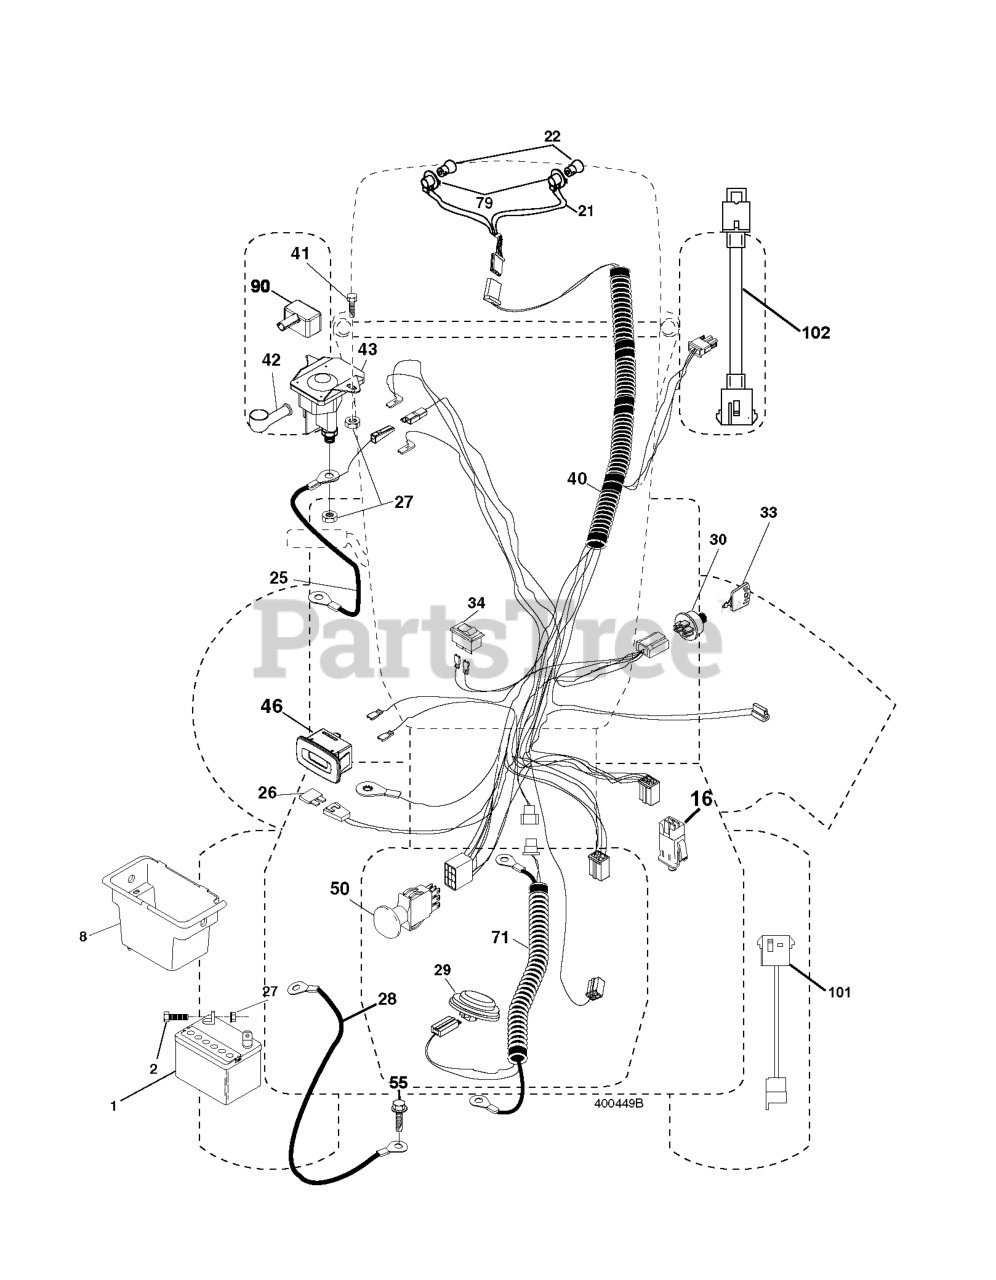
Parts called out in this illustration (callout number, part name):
1	BATTERY 12V .35 AMP
2	BOLT.HEX.1/4.X.3/4.DICHROMATE
8	BOX.BATTERY.MNT.REAR.L
16	SWITCH INTERLOOK PUSH-IN
21	HARNESS.LIGHT W/4152J BULBS
25	CABLE.STARTER.6GA.RED.
26	FUSE 20AMP
27	NUT
28	CABLE.BLACK.18"REAR.BA
29	SWITCH.SEAT.DELTA.OPC.
30	SWITCH.IGN.DELTA.W.LGH.ROS
33	KEY MLD GEN DELTA
40	HARNESS.IGN.DASH.HUQ/P
41	SCREW
42	TERMINAL COVER
43	SOLENOID.W/BRASS.PLUNGER
46	RP.GUAGE.SRVCMNDR.HRMTR.
50	RP.PTO.SWITCH.8 TERMINAL.BLACK
55	SCREW 5/16"
71	HARNESS.IGN.CHASS.TEX.REAR.BAT
79	BULB HOLDER ASM.
90	COVER, TERMINAL BATTERY
101	PIGTAIL.MATNLK.NEW.HAR
102	HARNESS PIGTAIL PCH TEX ROS
